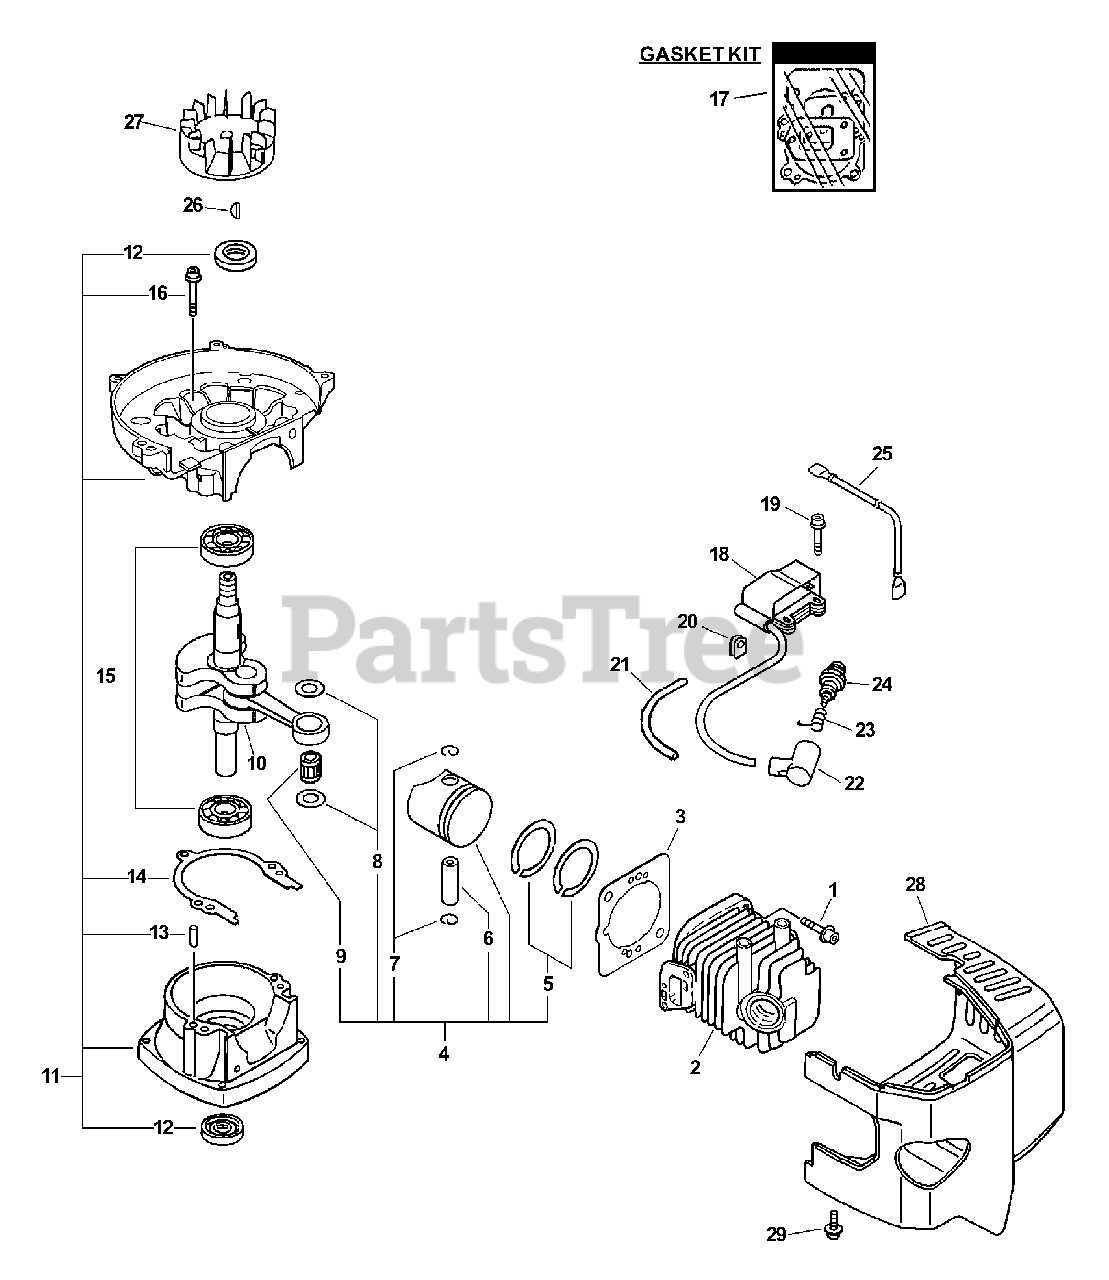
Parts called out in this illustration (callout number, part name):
1	BOLT 5×22
2	CYLINDER
3	GASKET, CYLINDER
4	PISTON KIT
5	RING, PISTON
6	PIN, PISTON 8
7	RING, SNAP
8	WASHER, THRUST
9	BEARING, NEEDLE 8
10	CRANKSHAFT ASSY
11	CRANKCASE KIT
12	SEAL, OIL 12
13	PIN, LOCATING 4
14	GASKET, CRANKCASE
15	BEARING, BALL - 6201 C3
16	BOLT 5×28
17	GASKET KIT
18	COIL, IGNITION
19	BOLT 4×20
21	TUBE, INSULATOR
22	CAP, SPARK PLUG
23	TERMINAL, SPARK PLUG
24	SPARK PLUG - BPM8Y
25	LEAD
27	FLYWHEEL
28	COVER, CYLINDER
29	SCREW 4×18
